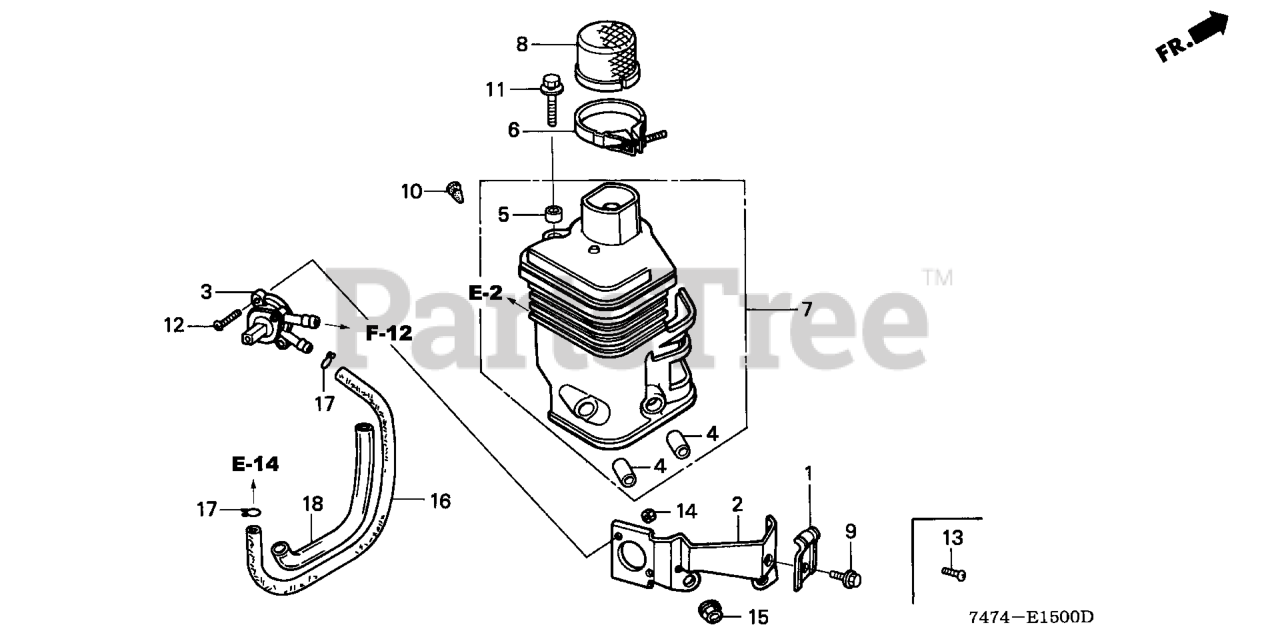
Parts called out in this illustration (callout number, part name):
1	HOLDER, CONTROL CABLE Use from Engine SN 2327377.
2	STAY, CHOKE CONTROL
3	PETCOCK ASSY.
4	COLLAR, AIR CLEANER Use from Engine SN 1786085.
5	COLLAR B, AIR CLEANER
7	ELBOW, AIR CLEANER
9	BOLT, FLANGE (5X10) Use from Engine SN 2327377.
10	PLUG, CONE TYPE
11	BOLT, FLANGE (6X20)
12	SCREW, PAN (3X12)
14	NUT, HEX. (3MM)
15	NUT, FLANGE (6MM)
16	BULK HOSE, FUEL (5.5X3000) (Honda Code 5338587). (5.5X150)
17	CLIP, TUBE (B10)
18	BULK HOSE, VINYL (11X13X3000) (11X13X210)
